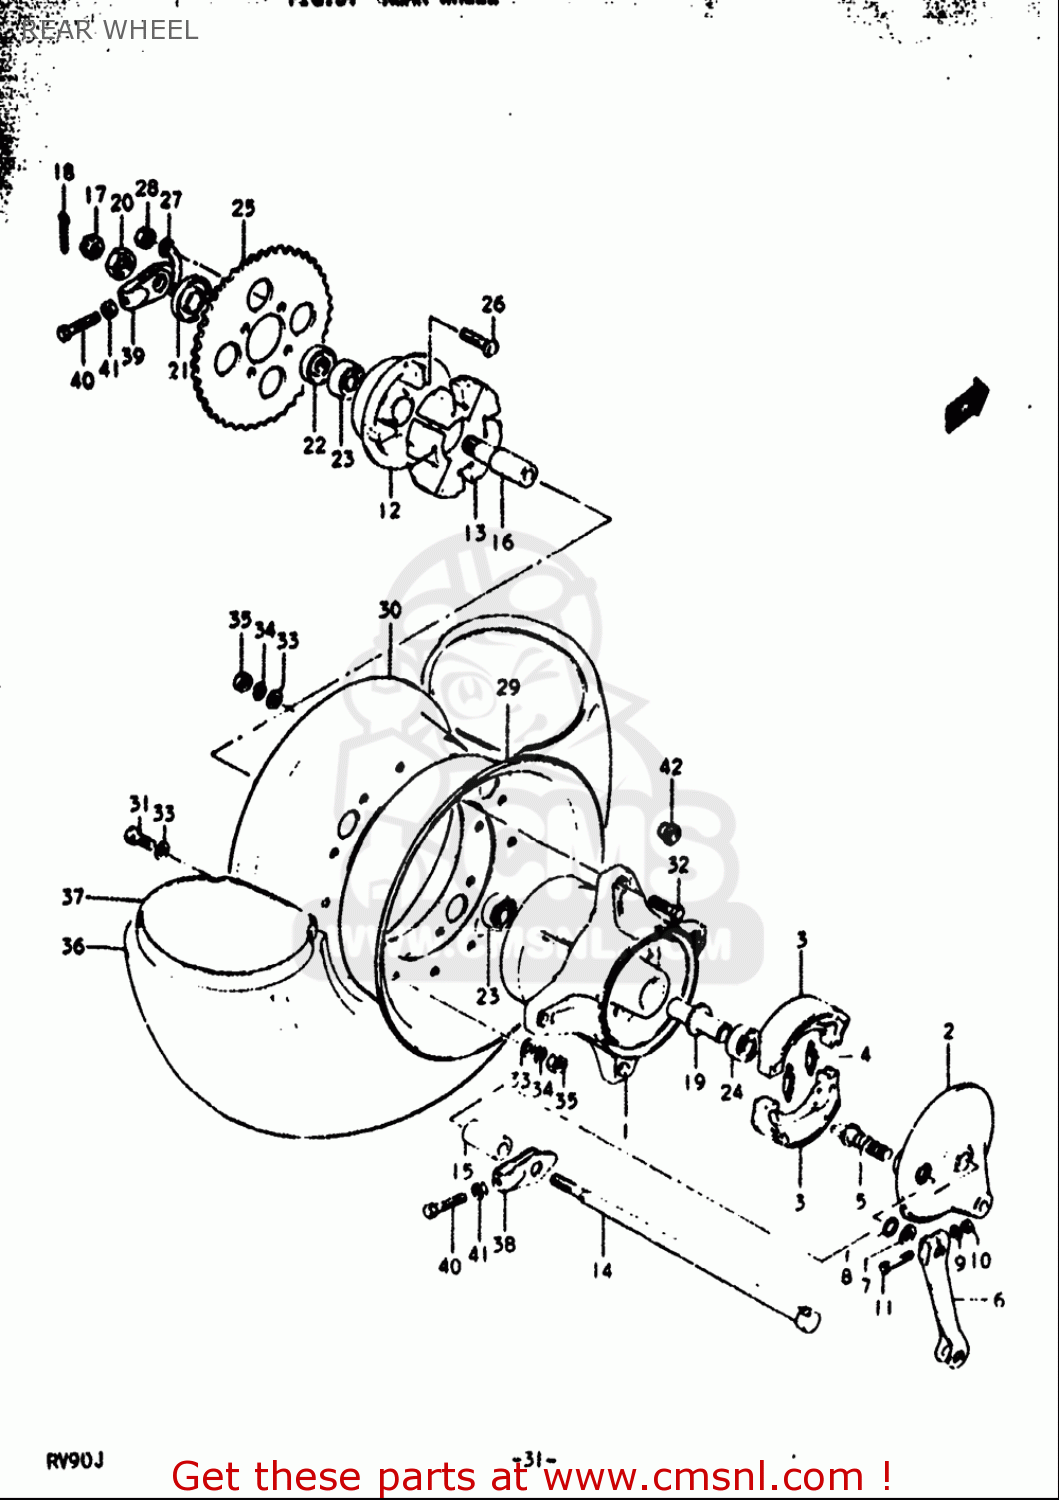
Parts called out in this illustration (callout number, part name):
3	SHOE & SPRING SET,BRAKE (NAS)
4	SPRING(L:35.8)
5	CAM,FR BRAKE
7	WASHER(12.5X20X1)
8	O RING(D:2.5,ID:11.4)
9	WASHER
10	NUT
11	BOLT(6X31)
12	DRUM,REAR SPROCKET MOUNT
13	ABSORBER,RR WHEEL HUB SHOCK
14	AXLE,RR
15	SPACER (12.2X22X37.7)
16	SHAFT,RR SPROCKET DRUM
17	NUT
18	COTTER PIN
20	NUT
21	SPACER,REAR SPROCKET DRUM
22	SEAL,OIL(25X40X6)
23	BEARING
24	BEARING(17X40X12)
25	SPROCKET,REAR (NT:31)
26	BOLT(8X33.5)
27	WASHER
29	RIM,WHEEL RH
31	BOLT
32	BOLT
33	WASHER
34	WASHER,LOCK
35	NUT
36	TIRE. (BRIDGESTONE)
37	TUBE,INNER
38	ADJUSTER,CHAIN,R
39	ADJUSTER,CHAIN,L
40	BOLT(6X38)
41	NUT
